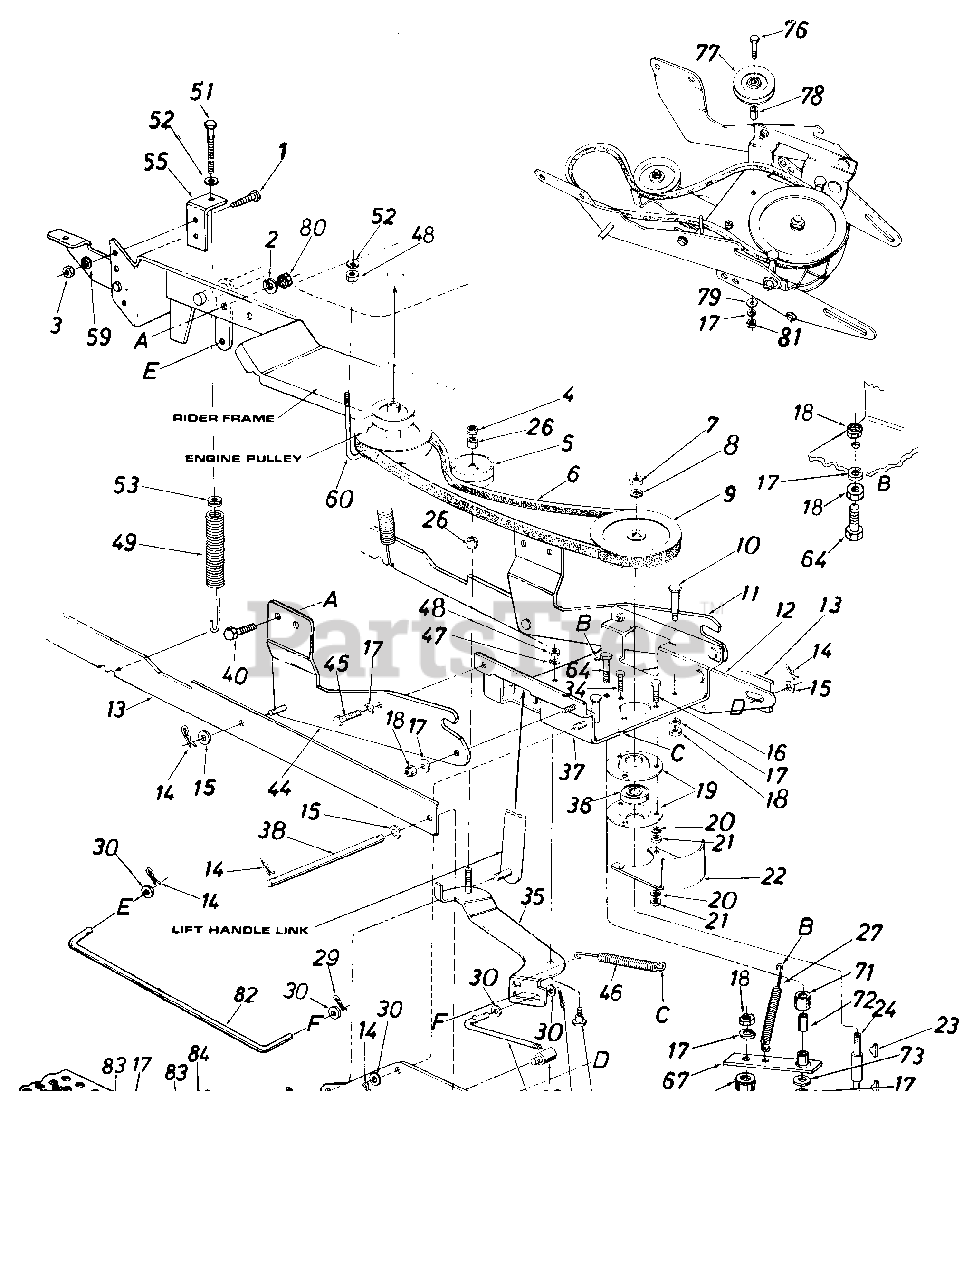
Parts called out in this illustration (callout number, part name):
1	Hex Bolt 1/4-28 x 1.00" Lg. Grade 5
2	L.-Wash. 1/4" I.D.
3	Hex Nut 1/4-28 Thd.
4	Hex Cent. L-Nut 3/8-16 Thd.
5	Idler Pulley
6	"V"Belt
7	Hex Jam Nut 5/8-11 Thd.
8	L. Wash. 5/8" I.D.
9	6.50" O.D. x 5/8 Pulley
10	Shoulder Bolt
11	Channel Support Brkt.-R.H.
12	Linkage Brkt.
13	Linkage Arm Ass'y.
14	Intern. Cotter Pin .50 Dia.
15	Fl.-Wash.
16	Hex Bolt 5/16 x 1.25" Lg.
17	L.-Wash. 3/8" I.D.
18	Hex Jam Nut 3/8-16 Thd.
19	Bearing Housing
20	L.-Wash. 5/16" I.D.
21	Hex Nut 5/16-18 Thd.
24	Pulley Spindle
25	5/8 Pulley-6.28 I.D. x 5.56 O.D.
26	Spacer .383 I.D. x .503 O.D. x .562 Lg.
27	Extension Spring .54 O.D. x 5.25"
28	Shoulder Bolt
29	Cotter Pin 3/32" Dia.
30	Fl.-Wash.
31	Control Rod
32	Ferrule
34	Hex Sems Scr. 5/16-18 x .75" Lg.
35	Clutch Idler Brkt. Ass'y.
36	Ball Bearing
37	Channel Ass'y.
38	Lift Handle Shaft
40	Hex Self-Tap Scr. 1/4-20 x .75" Lg.
44	Channel Supporting Brkt. L.H.
45	Hex Bolt 3/8-16 x 1.0" Lg.
46	Extension spring
47	L.-Wash. 5/16" I.D.
48	Hex Nut 5/16-18 Thd.
49	Helper Spring
51	Hex Scr. 5/16-18 x 2.0" Lg. Special
52	Bell Wash. .345 I.D. x .88 0. D. x .06
53	Spring Insert
60	J.-Bolt 5/16-18 Thd.
62	"V" Belt 1/2 "A" x .89" Lg.
64	Hex Bolt 3/8-16 x 2.0" Lg.
65	Idler Pulley
66	Spacer .385 I.D. x .503 O.D. x .562" Lg.
67	Idler Arm Ass'y.
71	Spacer.380" I.D.
72	Spacer.3775 I.D. x .60 O.D. x 8.3 Lg.
73	Fl.-Wash. 3/8 I.D. x 1" O.D. x 1.27
76	Hex Bolt 3/8-16 x 2.5" Lg. (Grade 5) 6
77	Idler Pulley .38 I.D. x 3.06 O.D.
78	Spacer.385 I.D. x .630 O.D. x .76 Lg.
79	Fl.-Wash. .39 I.D. x 1-3/4 O.D. x 3/16"
80	Hex L-Nut 1/4-20 Thd.
81	Hex Nut 3/8-16 Thd.
82	Clutch Control Rod
83	Hex Nut 3/8-24 Thd.*
84	Hex Bolt 3/8-24 x 2.25" Lg.*
